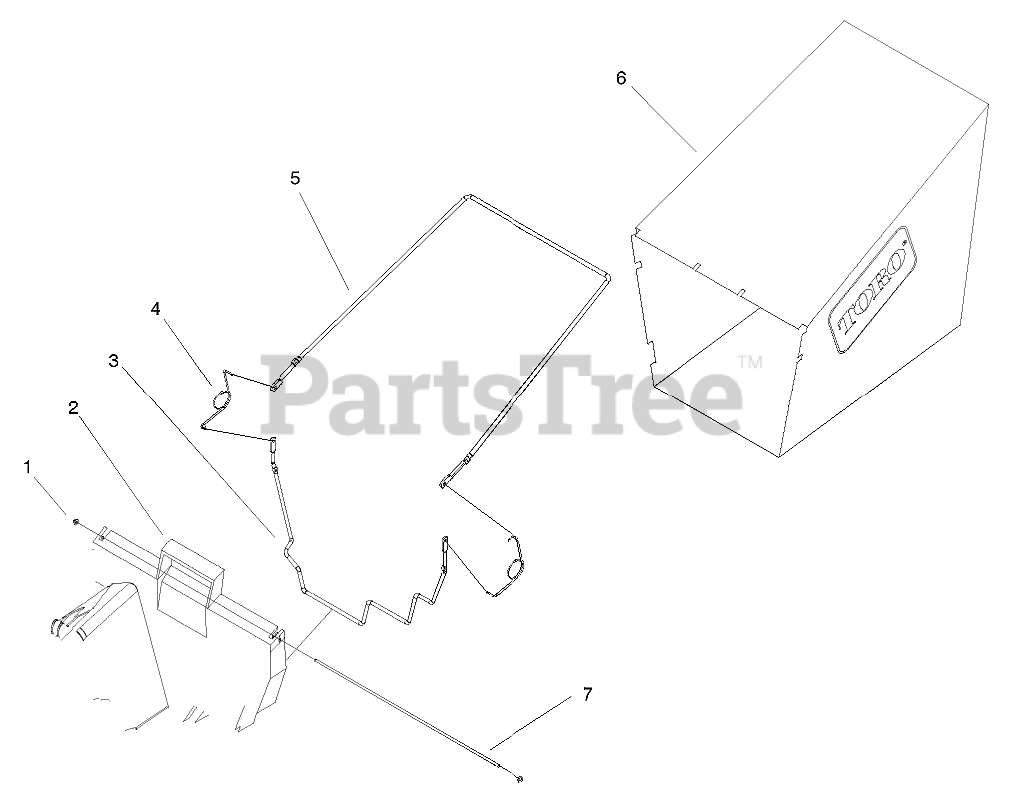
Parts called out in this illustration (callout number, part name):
1	NUT-PUSH
2	DOOR-BAG
3	FRAME-LOWER BAG
4	SPRING
5	FRAME-UPPER BAG
6	BAG-GRASS
7	HINGE-BAG DOOR
